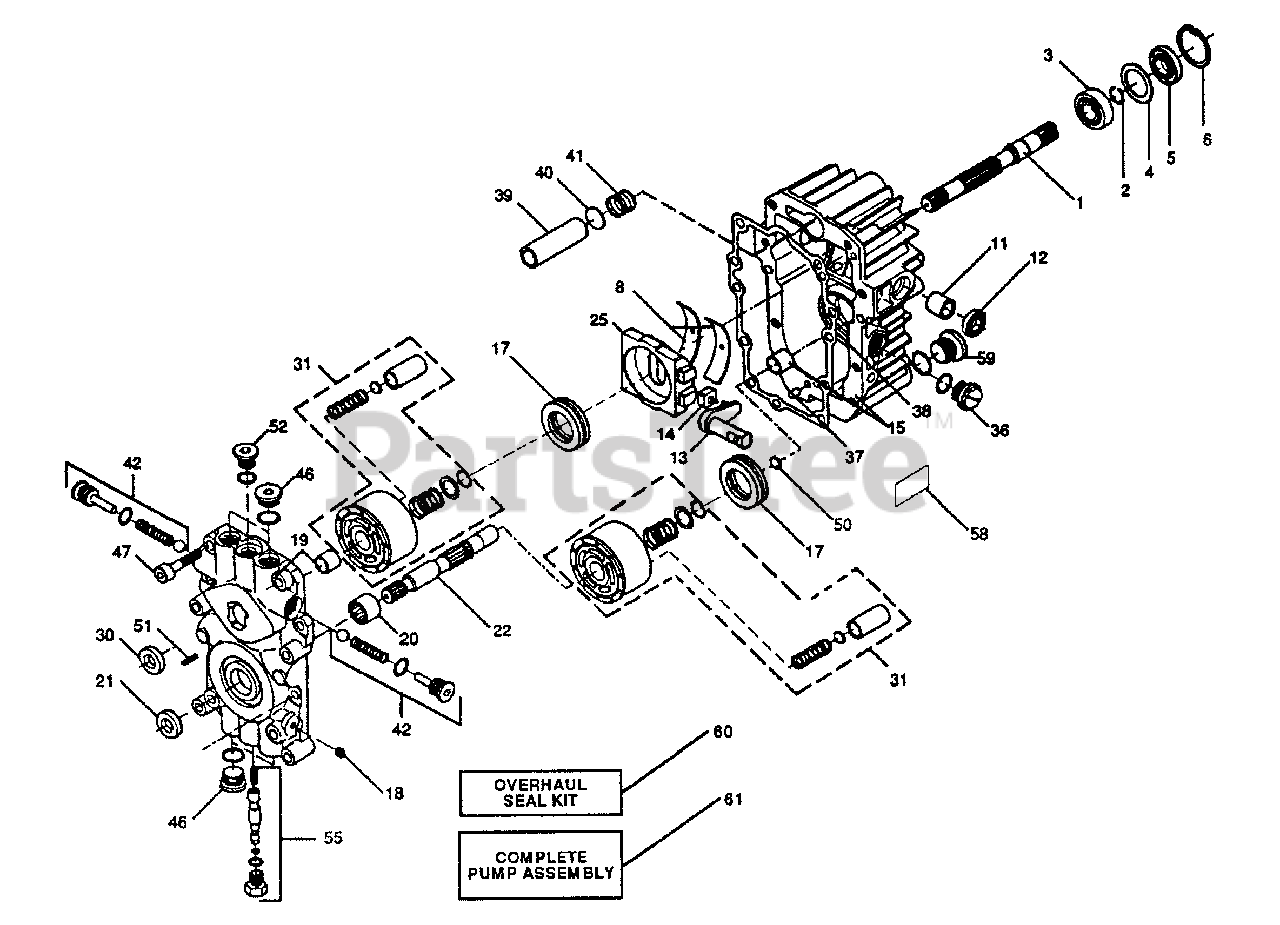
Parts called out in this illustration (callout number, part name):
1	Shaft, Pump
2	Ring, Retaining
3	Bearing, Ball
5	Seal, Lip
6	Ring, Retaining
8	Bearing, Cradle
11	Bearing, Journal
13	Arm, Trunnion
14	Guide, Slot
15	Housing Kit, Transmission
17	Bearing, Thrust Ball
18	Plug, Pipe
19	Center Section Kit
20	Bearing, Needle
22	Shaft, Motor
25	Swashplate, Variable
31	Block Kit, Cylinder (PUMP)
32	Block Kit, Cylinder (MOTOR)
36	Plug, Plastic
37	Pin, St. Hdls.
38	Gasket, Center Section
40	Washer, Thrust
41	Spring, Helical Compression
42	Check Valve Kit
46	Plug, St. Thd.
47	Screw Socket Head Cap
50	Washer, Thrust
51	Pin, Spiral
52	Plug, St, Thd.
55	Bypass Valve Kit
58	Adhesive Label, Bar Coded
59	Plug, St. Thd.
60	Overhaul Seal Kit, BDU-10
61	Complete Pump Assembly
